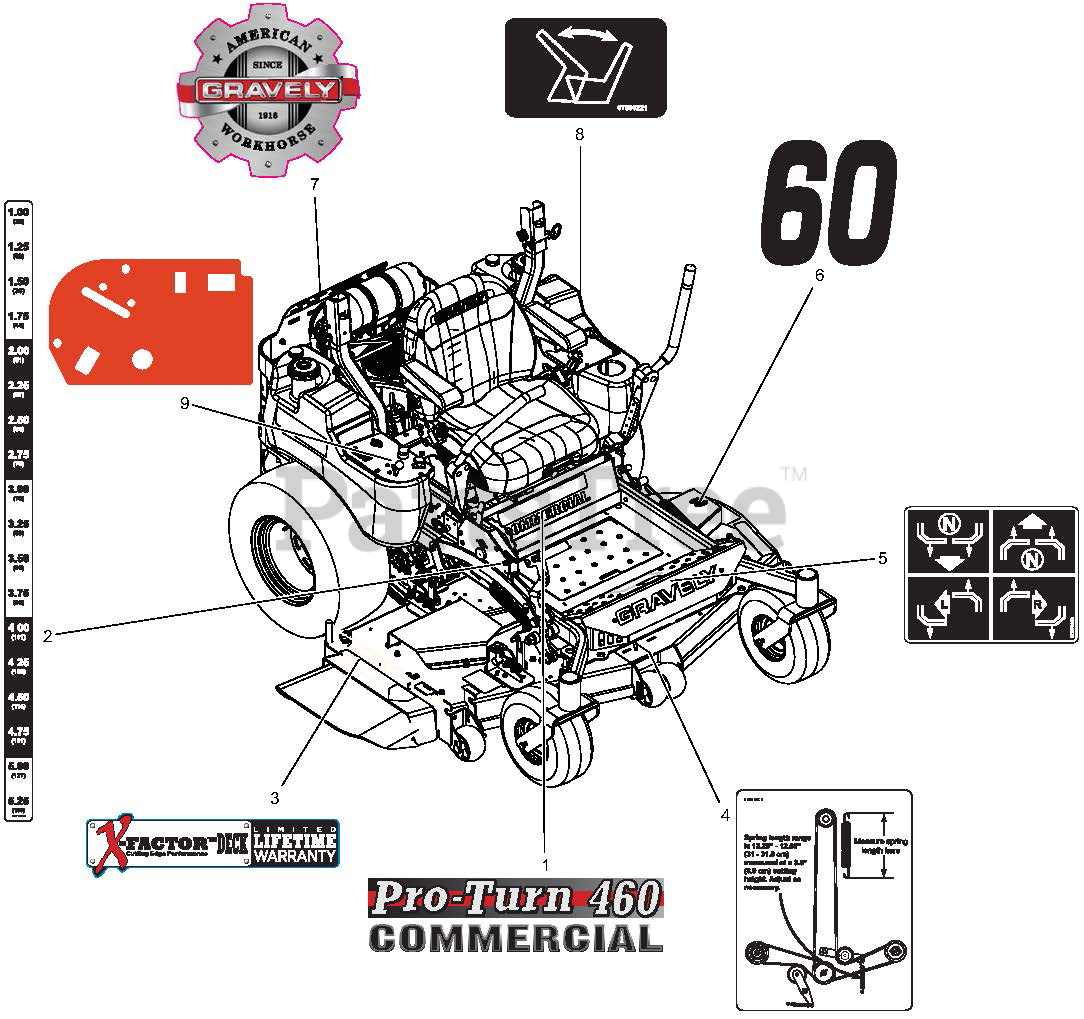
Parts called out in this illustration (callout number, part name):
1	DECAL, PT460
2	DECAL, PT400 HEIGHT OF CUT
3	DECAL, X-FACTOR DECK
4	DECAL, BELT DIAGRAM
5	DECAL, INSTRUCTIONAL - STEERING
6	DECAL, 60"
7	DECAL, GRAVELY HERITAGE-LARGE
8	DECAL, SEAT RELEASE
9	DECAL, EFI CONTROL PANEL
